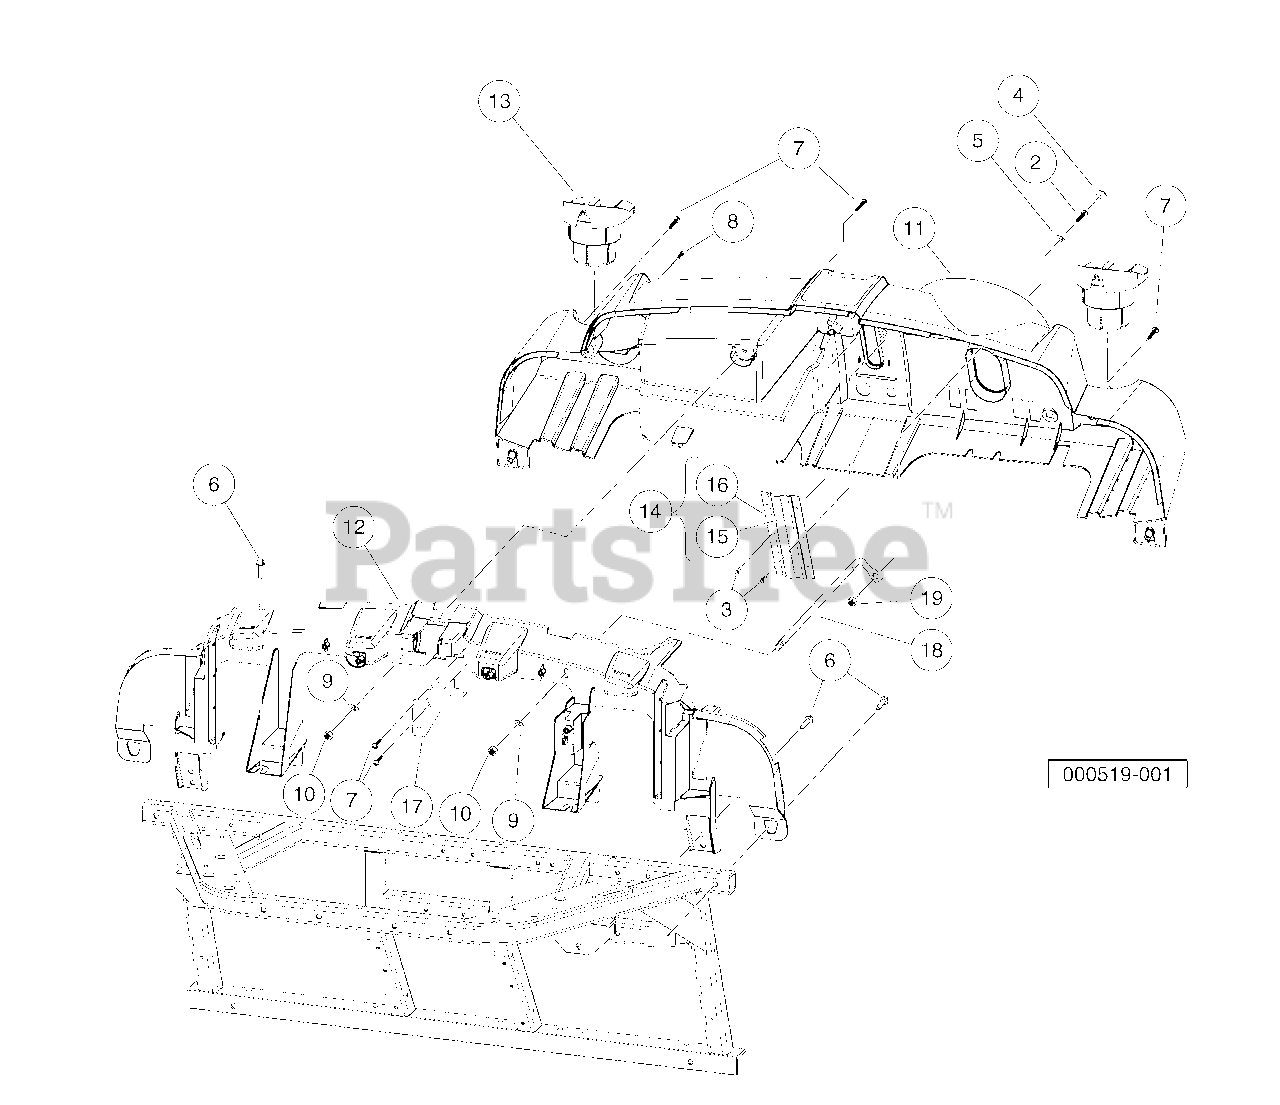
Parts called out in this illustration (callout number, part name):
1	Instl, Dash
2	Screw, 1/4-20 X 1.50 Hex-Head Cap
3	Screw, #8 X 0.500, Hex-Head Hi-Lo
4	Cap, 1/4" Plastic Screw Head
5	Washer, 1/4 Id Scalloped Plast
6	Screw, M8X1.25X30, Hex
7	Screw,m6,torx,interlock,thread
8	M8-1.25 X 80 Sems
9	Washer Hard,m10
10	Lock Nut, Flg M8 X 1.25 Nylon
11	Dash, Design A
12	Support, Structural
13	Cup Holder, Utility
14	Asm, Brush, Fnr
15	Brush, Strip, FNR
16	Holder, Brush, Strip, Fnr
17	Bracket, Hood Support
18	Rod, Connection, Dash
19	Locknut, 1/4-20 Nylon Insert
